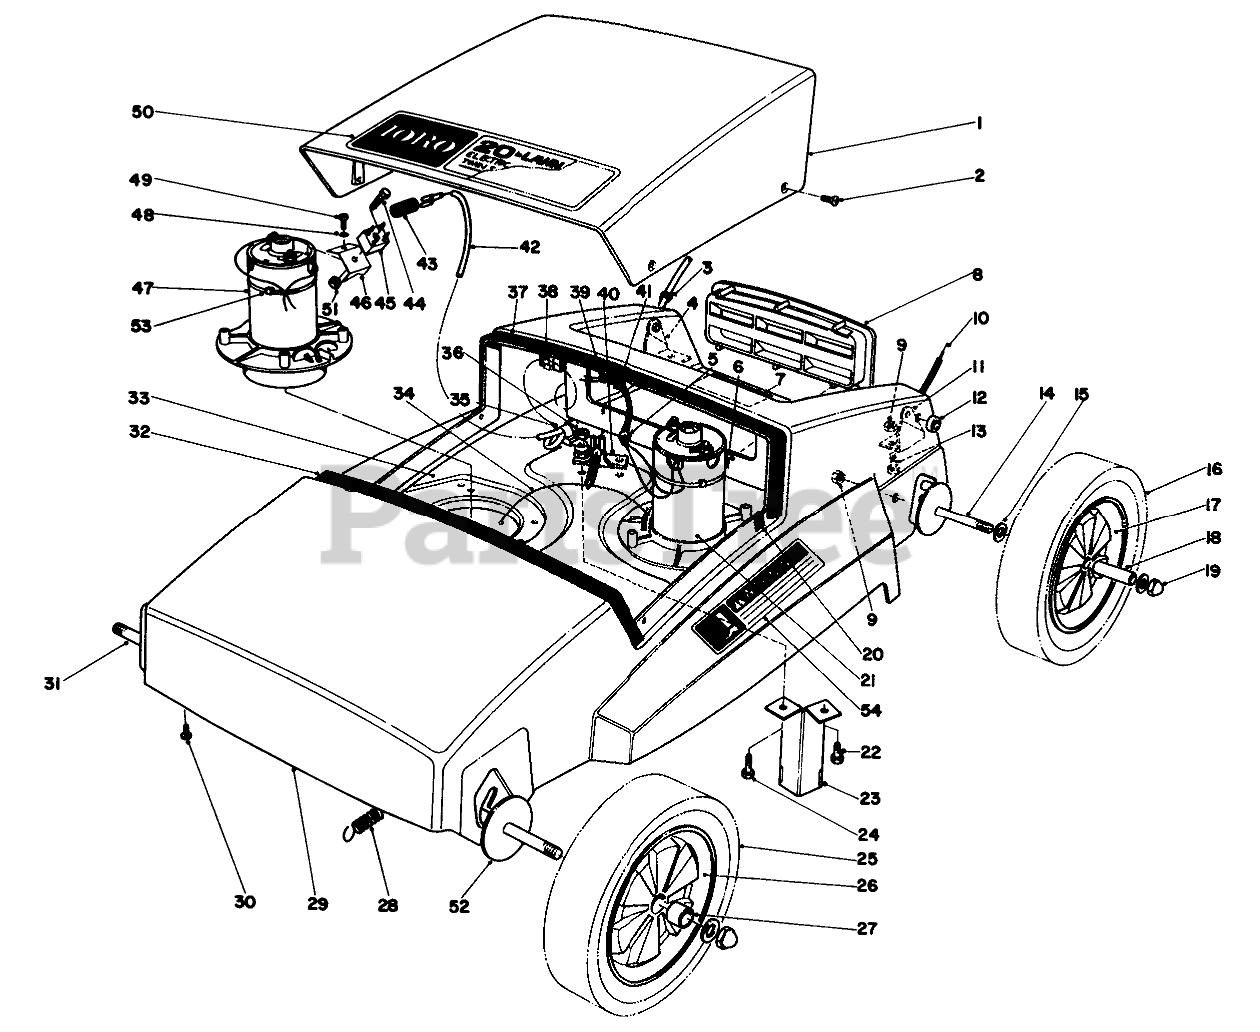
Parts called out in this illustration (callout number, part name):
1	Cover
3	5/16 ID BSHG
4	Handle Bracket R.H.
5	TIE-CABLE
6	Nut-Push On
7	Decal-Warning
8	Louver
9	NUT-LOCK, CONE
10	Control Cable-Upper
11	Handle Bracket L. H.
12	Spacer-Handle
13	SCREW-HH
14	Axle-Rear
15	WASHER-FLAT
17	Rear Wheel-8" (Incl. Ref. #16 & 27)
18	Spacer-Wheel
19	Locknut
20	Nut-Push On
21	Motor 1 H. (C.W.)
22	SCREW-HH
23	Blade-Cut Off
24	SCREW-HH
25	Tire 7"
26	Front Wheel-7" (Incl. Ref. #25 & 27)
27	BUSHING
28	Spring
29	Housing-Mower
30	Screw
31	Axle-Front
32	Cushion-Front
34	Control Cable-Lower
35	WIRE CLAMP
36	NUT-LOCK, CONE
37	Cushion-Rear
38	Clip-Power Cord
39	Sleeve-Motor Lead
40	Bracket-Control
41	Clip-Motor Lead
42	Wire Harness
43	Sleeve-Terminal Cover
44	SCREW-PPH
45	Rectifier
46	Bracket-Rectifier
47	Motor R.H. (C.C.W.)
48	WASHER-LOCK / EXT
50	Decal-Cover
51	NUT-LOCK
52	Washer-Axle
53	Strap
54	Decal-Caution, Deck
